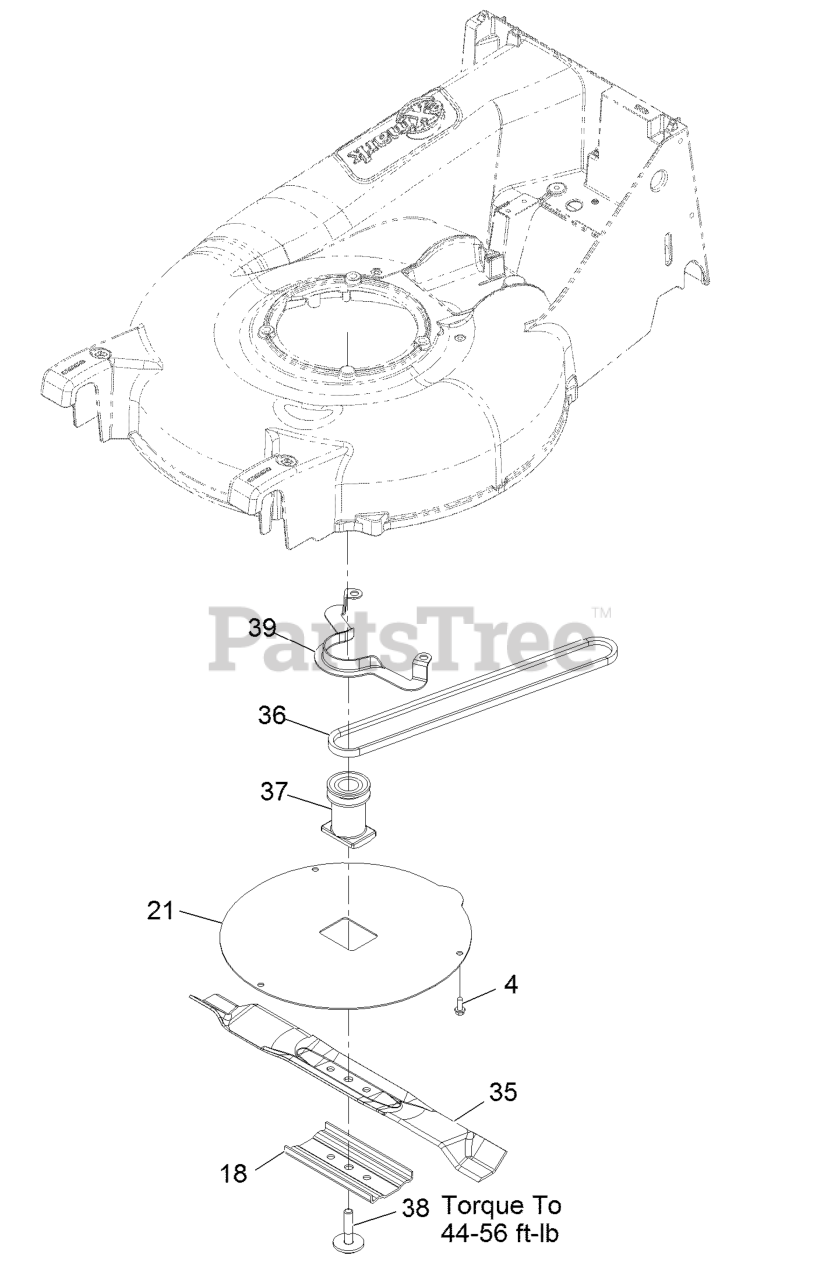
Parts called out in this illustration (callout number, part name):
4	Screw-HWH 1/4-20 X .62
18	Support-Blade
35	Blade - Medium Lift, 20.5
36	Belt,3L P21 Drive
37	Blade-Adapter
38	Bolt-Blade, Sem
39	Guide-Belt
